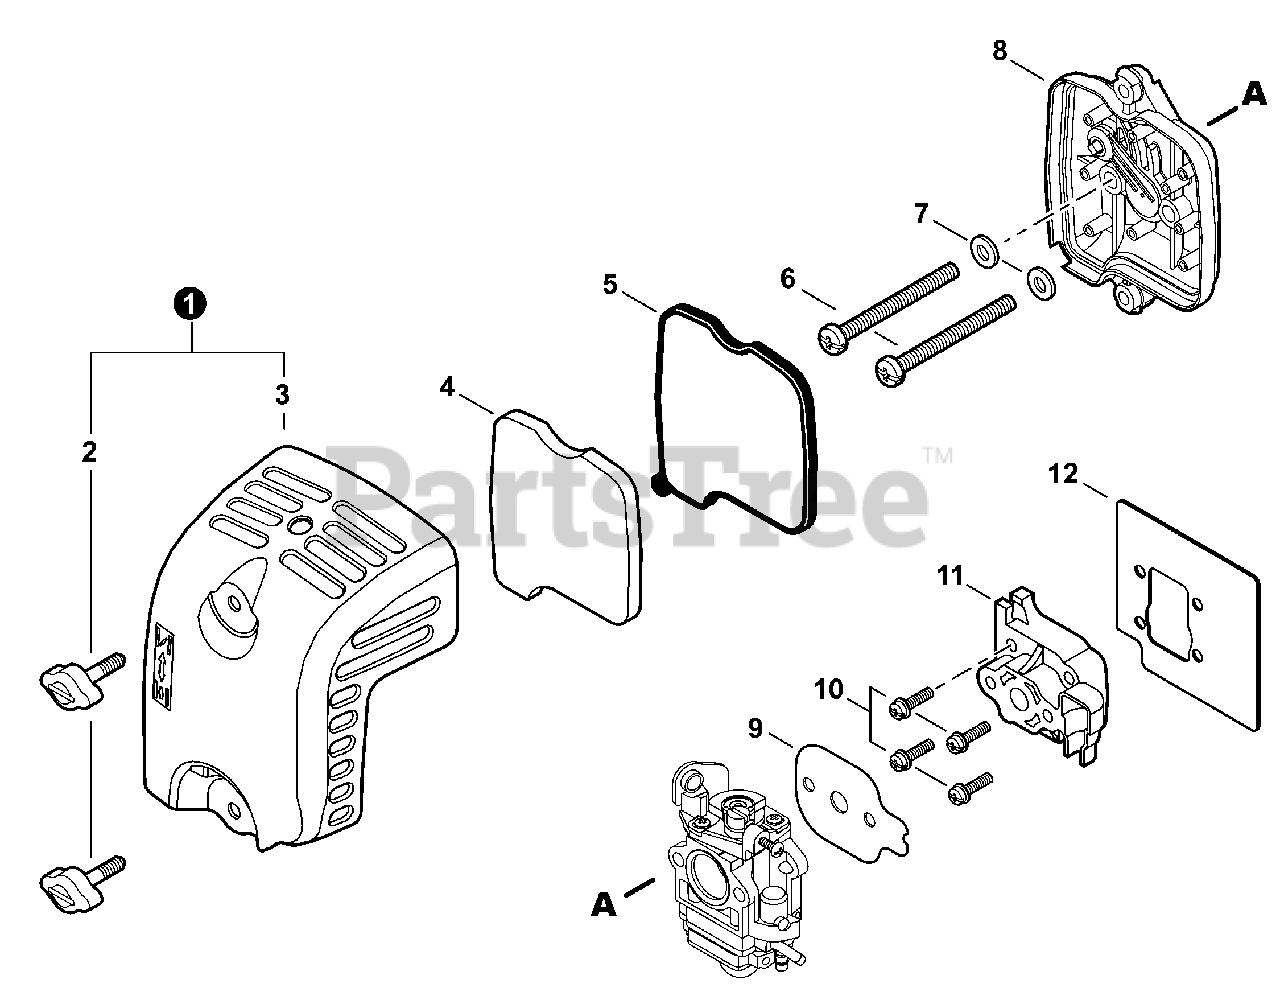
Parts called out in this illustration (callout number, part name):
1	COVER ASSY, AIR FILTER
2	THUMBSCREW M5
3	COVER, AIR FILTER
4	PRE-FILTER, FOAM
5	FILTER, AIR
6	SCREW M5×60
7	WASHER 5.5×12×0.8
8	CASE, AIR FILTER
9	GASKET, CARBURETOR
10	SCREW M5×25
11	INSULATOR WITH REED VALVE
12	HEAT SHIELD, INTAKE
